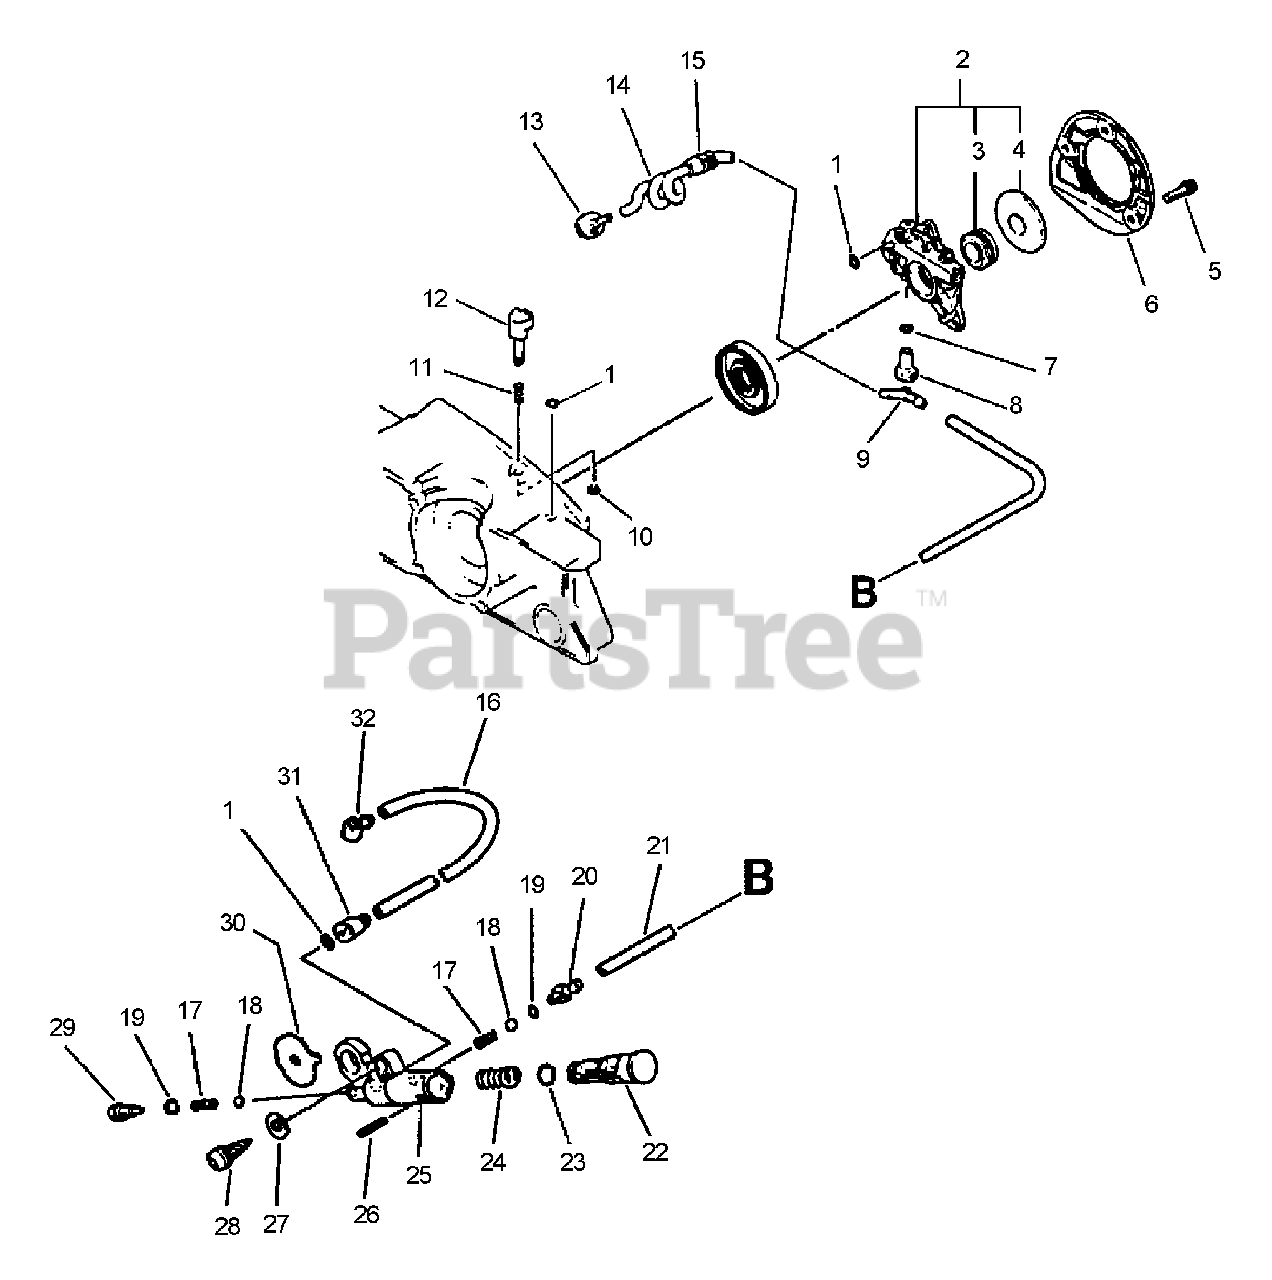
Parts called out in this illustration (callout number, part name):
1	O-RING 3
2	AUTO-OILER KIT
3	GEAR, WORM
5	BOLT 4×12
6	COVER, OIL PUMP - GRAY
7	CLIP Ø6.5 MM
8	CONNECTOR, PIPE
9	PIPE, OIL 3×6×20
10	E-RING 3
13	FILTER, OIL
14	PIPE, OIL
16	PIPE 3×6×125 BLACK
17	SPRING, VALVE
18	VALVE, BALL
20	CONNECTOR, PIPE
21	PIPE, OIL
22	PISTON, OIL PUMP - ORANGE
23	O-RING 7 MM
25	BODY, OIL PUMP
26	PIN, SPRING 2×16
27	WASHER 5.5×12×0.8
28	SCREW - 5×20
29	ADAPTOR, OIL PUMP
30	BRACKET, OIL PUMP
31	CONNECTOR, PIPE
32	CONNECTOR, PIPE
